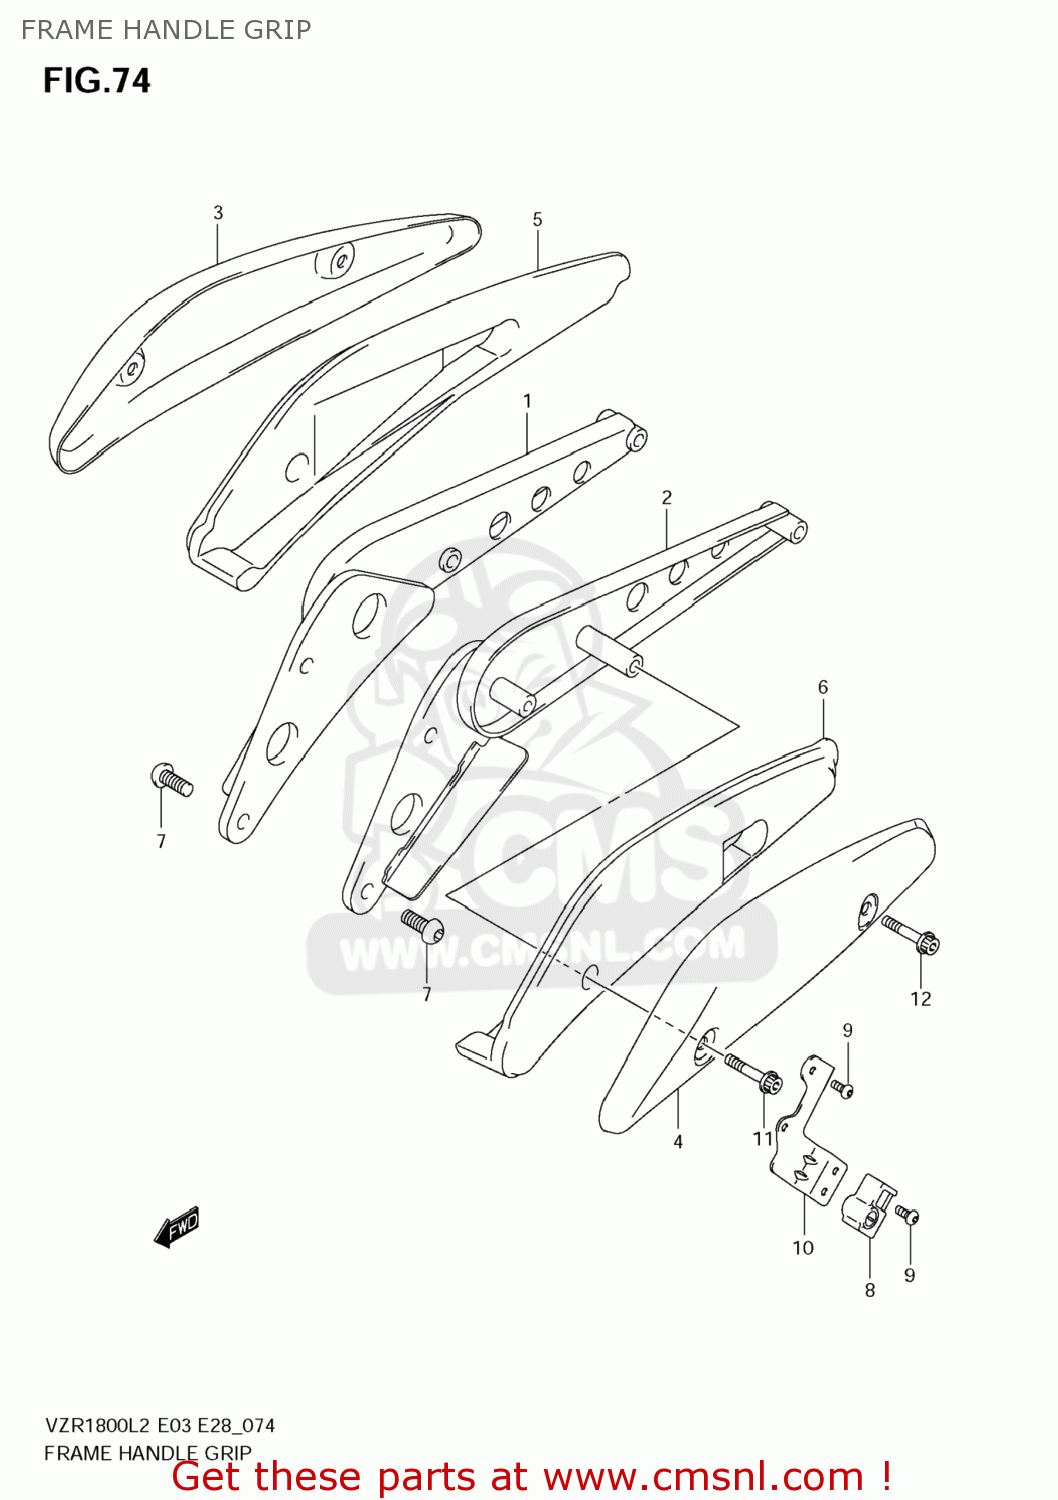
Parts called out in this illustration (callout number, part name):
1	GRIP,FRAME HANDLE,R
2	GRIP,FRAME HANDLE,L
3	PLATE,FRAME HANDLE,R
4	PLATE,FRAME HANDLE,L
5	RUBBER,FRAME HANDLE GRIP,R
6	RUBBER,FRAME HANDLE GRIP,L
7	BOLT(10X25)
8	LOCK SET,HELMET
9	SCREW(6X14)
10	BRACKET,HELMET LOCK
11	BOLT(8X70)
12	BOLT(8X50)
